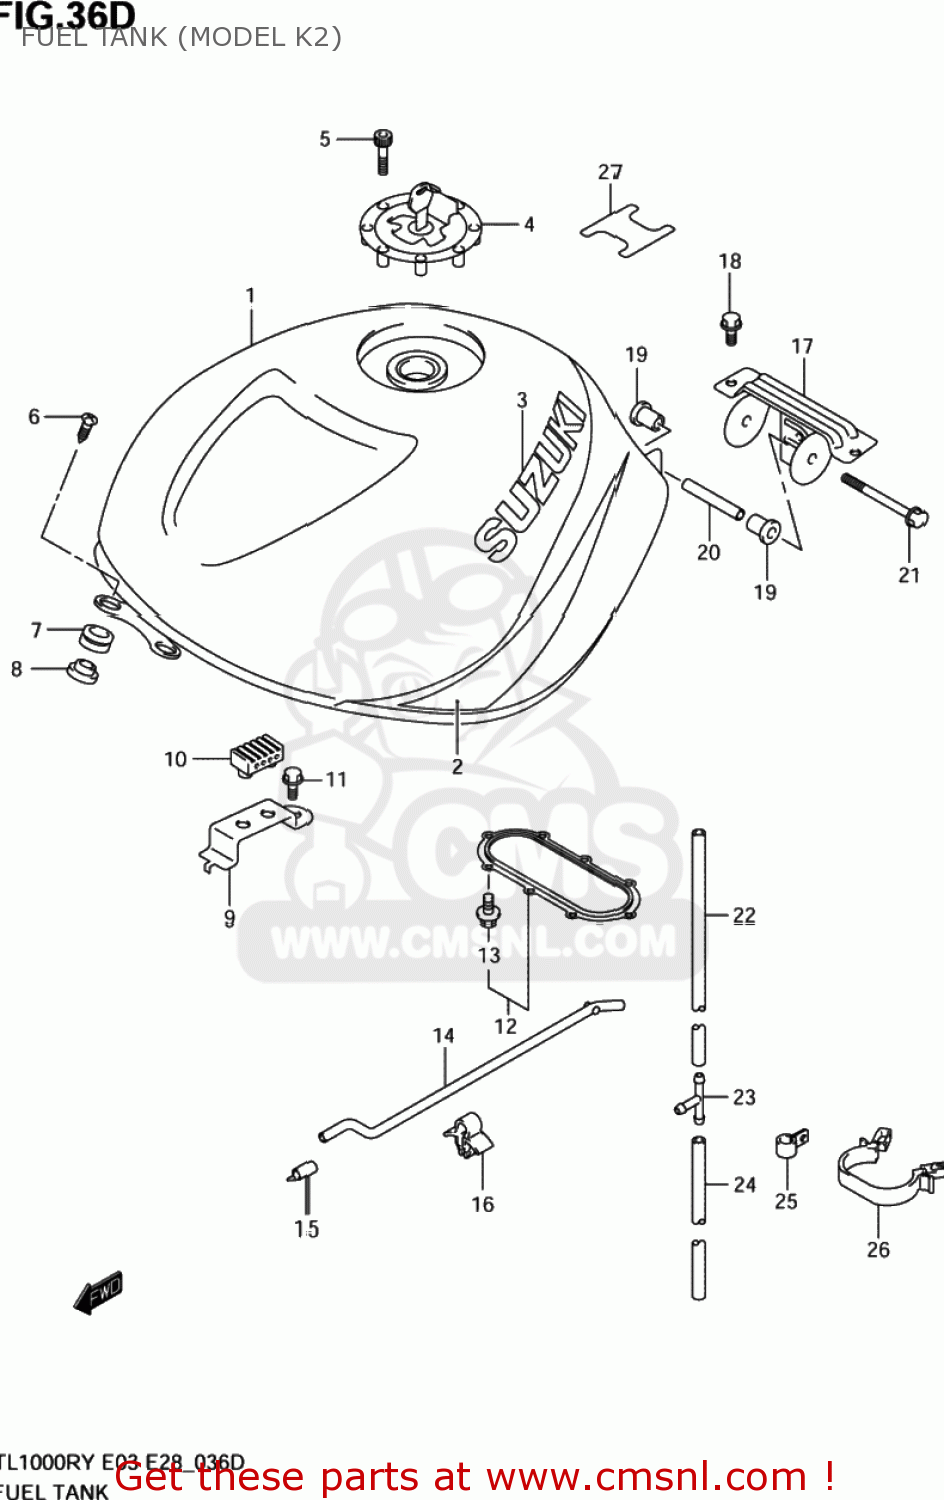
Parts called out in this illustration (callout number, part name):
1	TANK ASSY,FUEL
2	TAPE SET,FUEL TANK(BLUE)
3	EMBLEM,FUEL TANK
4	CAP SET,FUEL TANK
5	BOLT(5X20)
6	SCREW(6X25)
7	CUSHION
8	WASHER
9	BRACKET,FUEL TANK SIDE CUSHION
10	CUSHION,SEAT(40X20X15)
11	BOLT
12	PACKING SET,FUEL PUMP (NAS)
13	BOLT(5X10)
14	STAY,FUEL TANK
15	CAP,OD:11
16	CLAMP
17	BRACKET,FUEL TANK RR
18	BOLT
19	CUSHION,FUEL TANK RR
20	SPACER,FUEL TANK RR
21	BOLT
22	HOSE,FUEL TANK DRAIN
23	3 WAY
24	HOSE(7X10.2X600)
25	CLAMP
26	CLAMP
27	LABEL,FUEL TANK INNER
